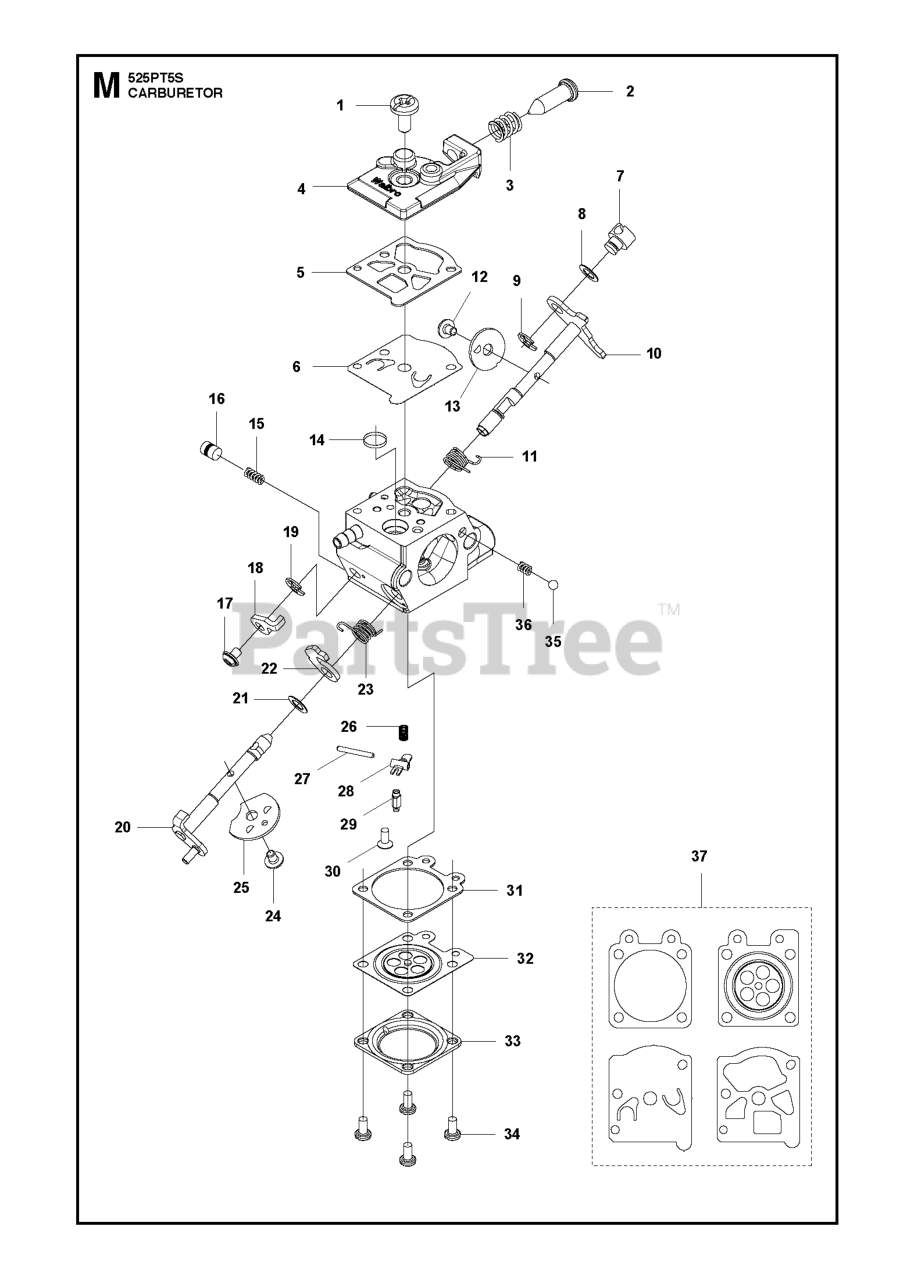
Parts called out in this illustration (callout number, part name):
2	SCREW, IDLE
4	COVER PUMP
6	PUMP DIAPHRAGM
10	SHAFT ASSEMBLY,THROTTLE
14	SCREEN
16	PISTON ASSY
18	LEVER THROTTLE
20	SHAFT ASSEMBLY,CHOKE
29	VALVE INLET
34	SCREW ASSY
36	CHOKE SPRING
37	GASKET KIT
